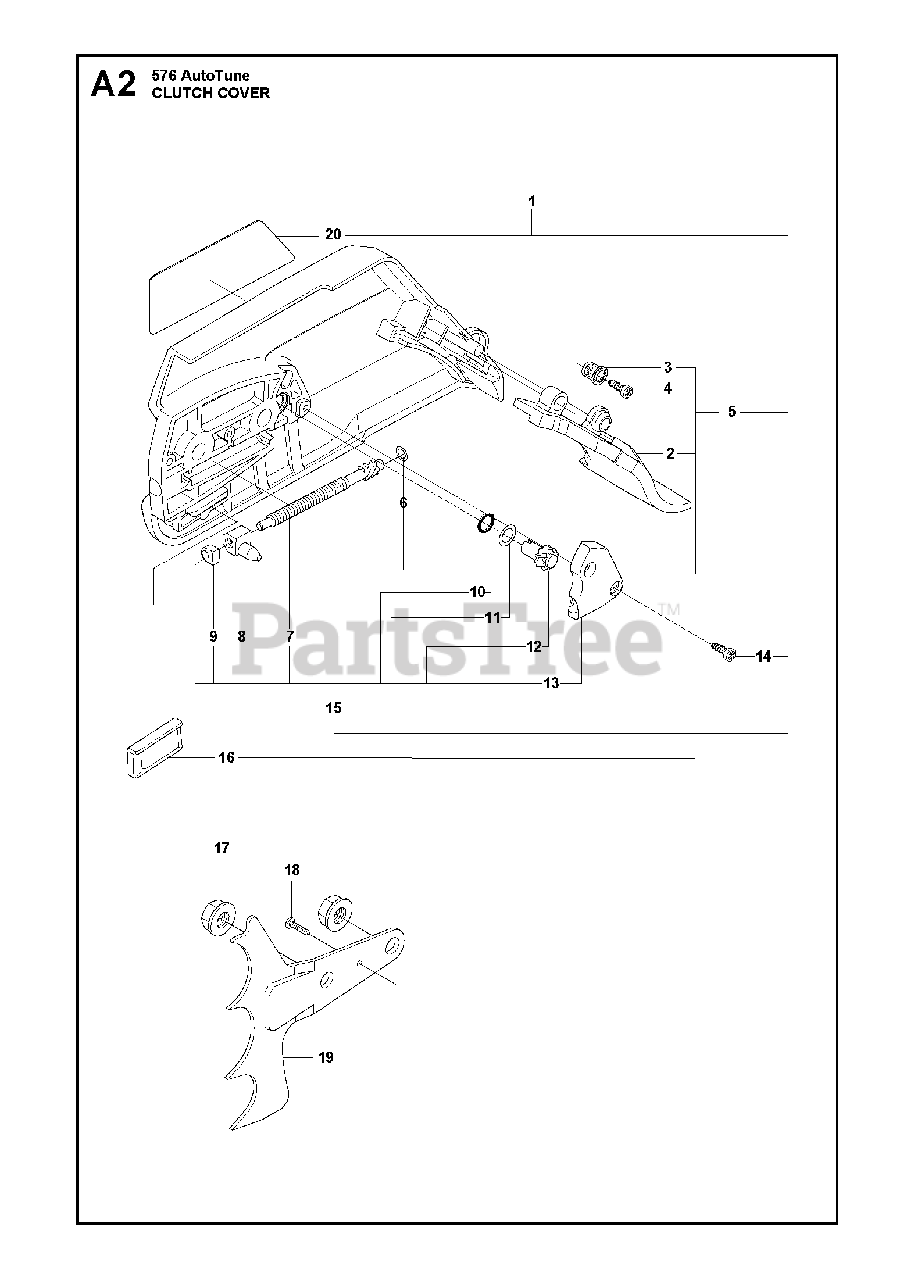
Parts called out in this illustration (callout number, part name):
1	CLUTCH COVER ASSY
2	PROTECTOR
3	WASHER
4	SCREW
5	CLUTCH COVER ASSY H SILVER R-
6	WASHER
7	ADJUSTER
8	PAWL
9	SLEEVE
10	O-RING
11	WASHER
12	RP ADJUSTER
13	COVER
14	SCREW
15	KIT-CHAIN TENSIONER
16	CHAIN GUIDE
17	NUT M8 FLANGE
19	SPIKE OUTER
20	DECAL
